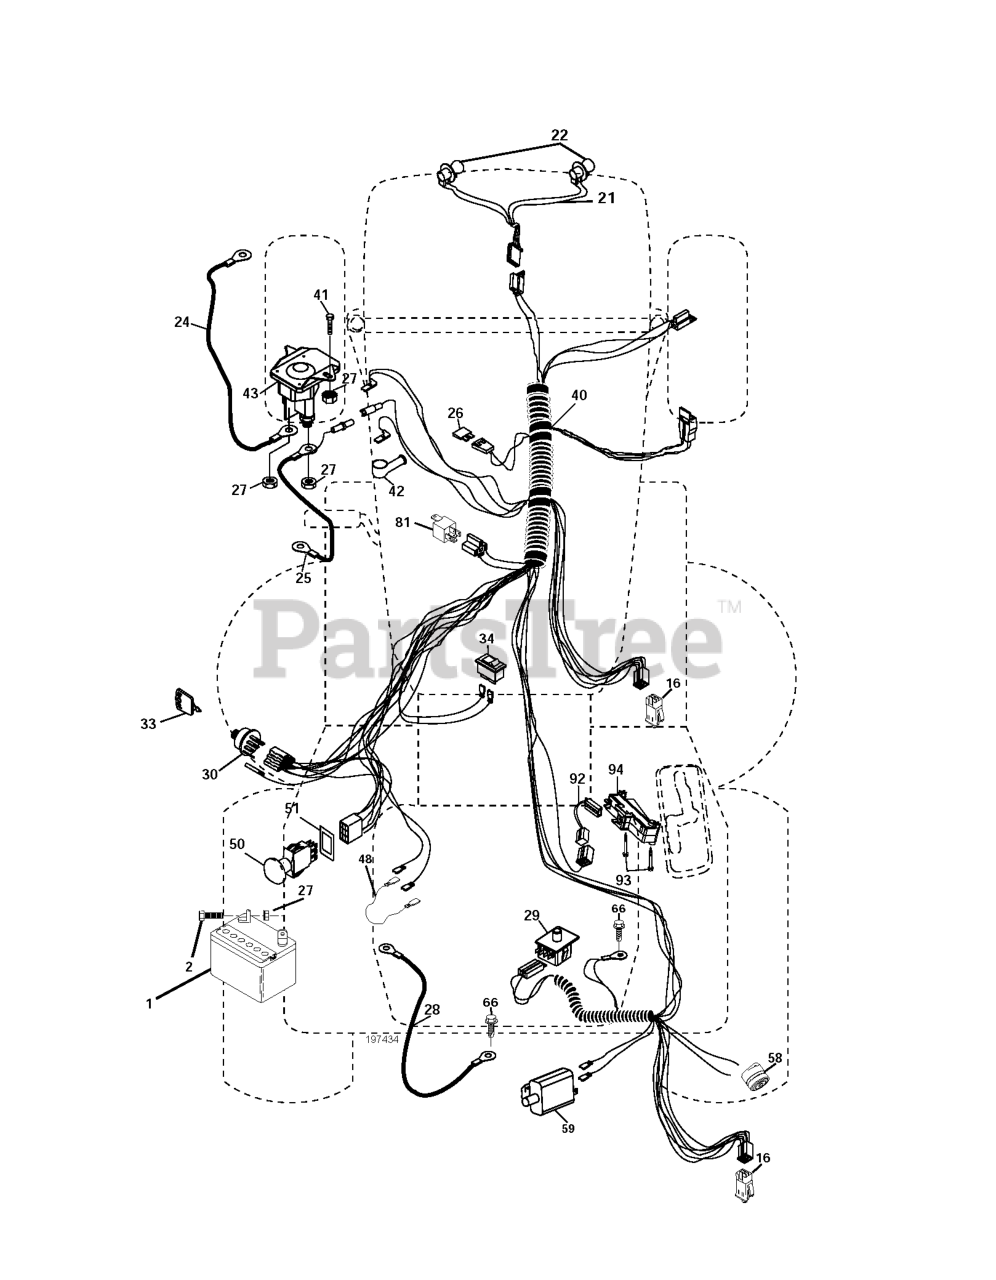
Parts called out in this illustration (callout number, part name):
1	BATTERY 12V .35 AMP
2	BOLT.HEX.1/4.X.3/4.DICHROMATE
16	SWITCH INTERLOOK PUSH-IN
21	HARNESS.W/LIGHT SOCKET
24	BATTERY CABLE GT
25	CABLE BATTERY
26	FUSE 20AMP
27	NUT
28	CABLE GROUND
29	SWITCH.SEAT.DP W/RAMPS
30	SWITCH.IGN.DELTA.W.LGH.ROS
33	KEY MLD GEN DELTA
40	RP HARNESS.IGN.ELECT.REG.CRD
41	BOLT
42	TERMINAL COVER
43	SOLENOID.W/BRASS.PLUNGER
48	ADAPTER.AMMETER
50	RP.PTO.SWITCH.8 TERMINAL.BLACK
51	FRAME RETAINING RING
52	WIRE PROTECTION LOOP
58	BUZZER
59	.WITCH.FULL BAGGER.INDICATOR
81	RELAY.ASSY.T
92	HARNESS.PIGTAIL.CONSLE
93	SCREW.PLASTITE
94	MODULE.REVERSE.ROS
